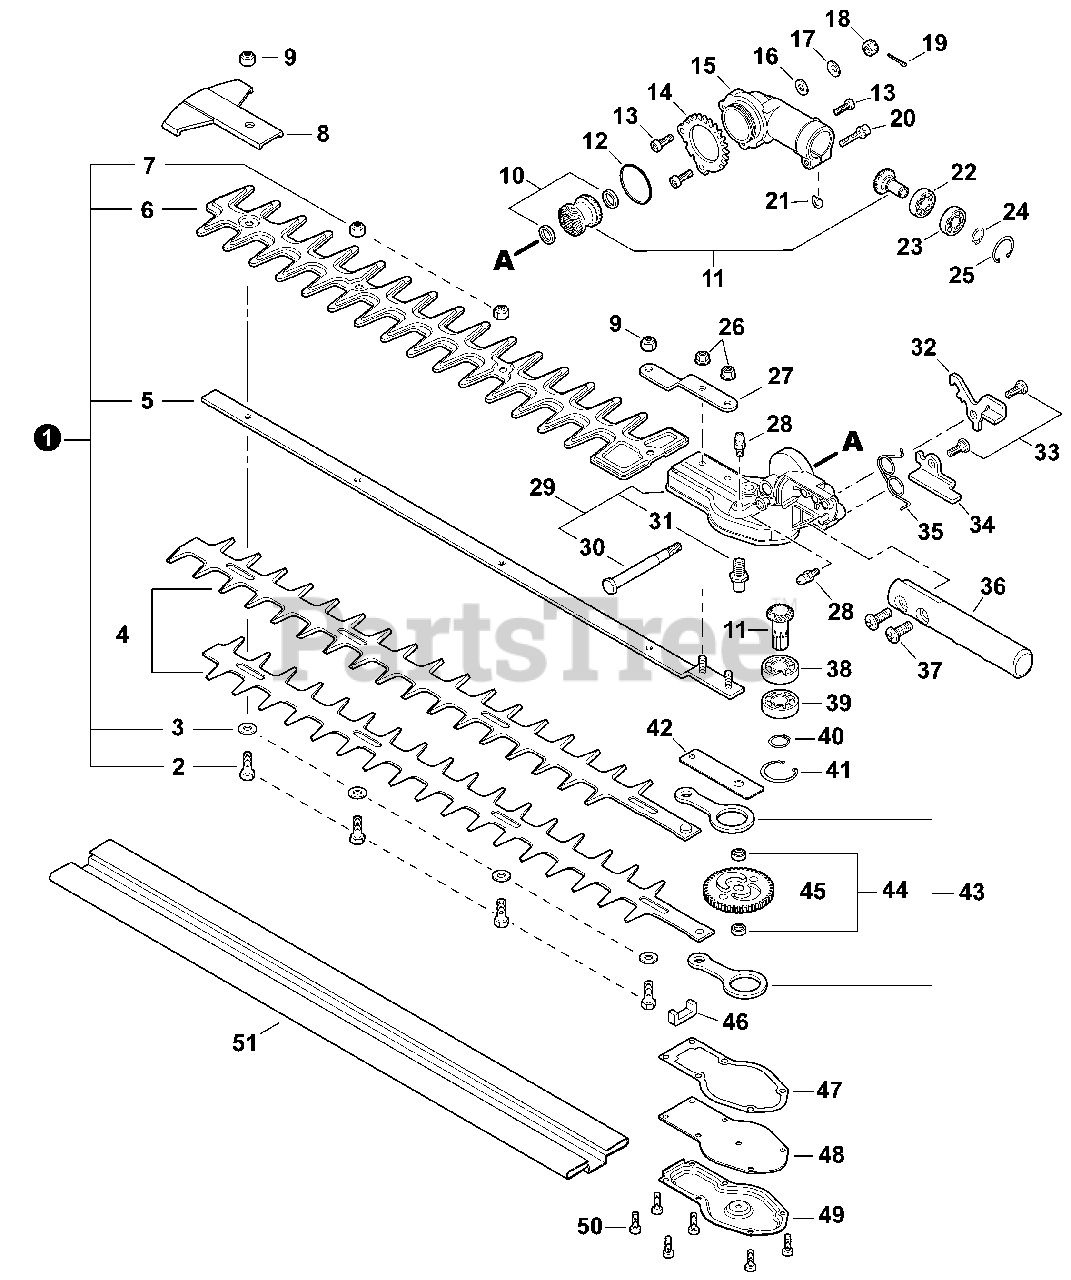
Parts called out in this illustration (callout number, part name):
1	CUTTER ASSY, 22"
2	BOLT M6×20
3	WASHER M6
4	CUTTER 22"
5	GUIDE BAR 22"
6	GUARD, CUTTER BLADE
8	GUARD, TIP
10	COLLAR Ø16ר10×L= 2
11	GEAR SET
13	BOLT 5×12
14	RING, LOCKING
15	HOUSING, UPPER GEAR CASE
16	WASHER 6.5×13×1
17	WASHER, CONE M6
19	PIN, COTTER Ø1.6×15
20	BOLT M5×25
21	D-WASHER
22	BEARING, BALL 609
23	BEARING, BALL 609ZZ
24	RING, SNAP Ø9
25	RING, SNAP Ø24
26	NUT, FLANGE M5
27	BRACKET, CUTTER
28	FITTING, GREASE
29	GEAR CASE HOUSING ASSY
31	MAINSHAFT
32	LEVER, LOCK
33	BOLT M6
34	RELEASE, LOCK
35	SPRING, TORSION
36	LEVER, ADJUSTMENT
37	SCREW, TRUSS M6×20
38	BEARING, BALL 6001
39	BEARING, BALL 6001ZZ
40	RING, SNAP Ø12
41	RING, SNAP Ø28
42	PLATE, GUIDE
44	SPACER Ø11ר8×3.4
45	GEAR, CAM
46	PACKING, FELT
47	GASKET, GEAR CASE
49	COVER, GEAR CASE
50	BOLT 4×10
51	SCABBARD
